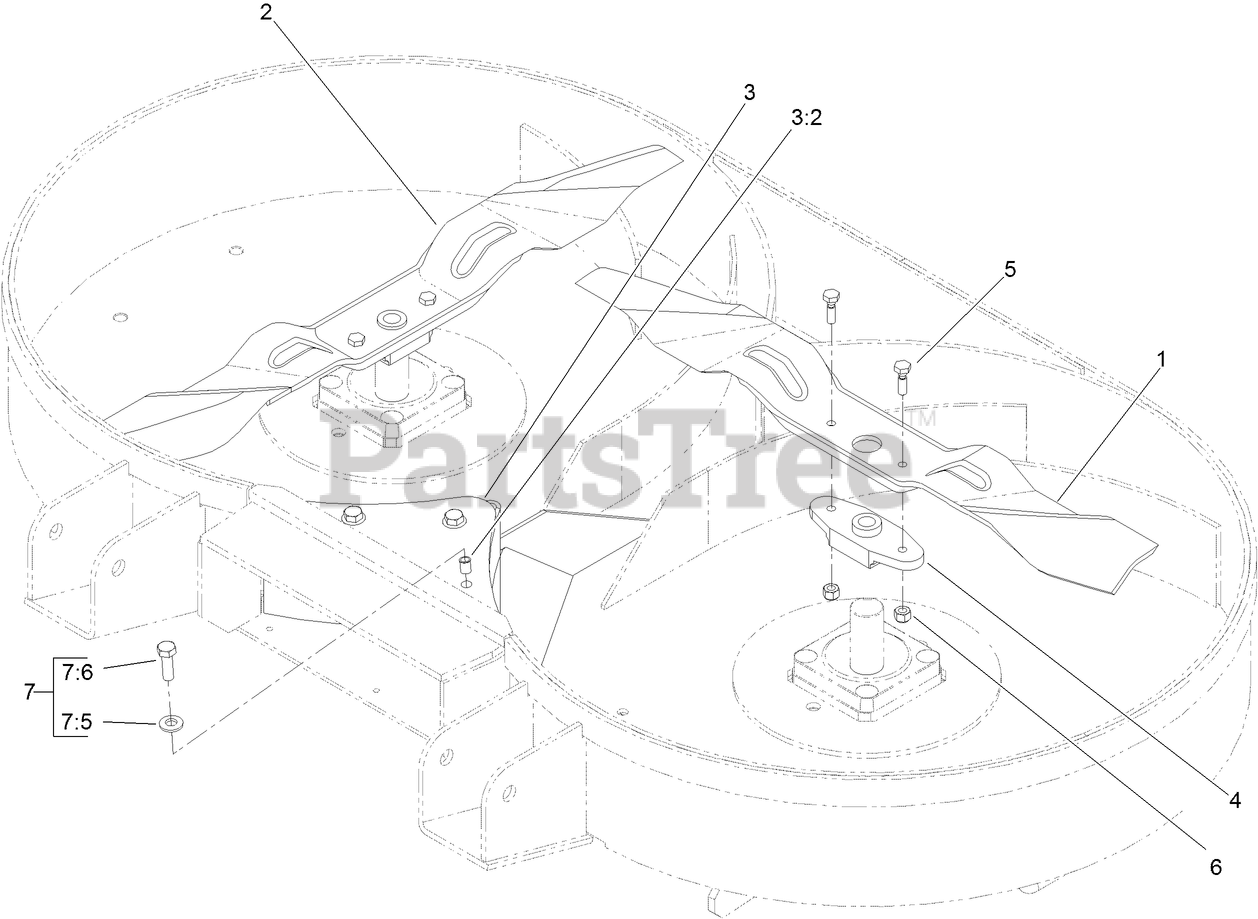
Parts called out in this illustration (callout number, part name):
1	BLADE-MULCHING, 22IN LH
2	BLADE-MULCHING, 22IN RH
3	MULCH PLUG ASM
3:2	NUT-INSERT
4	DRIVER-BLADE
5	BOLT-SHEAR
6	NUT-LOCK, NI
7	BOLT BAG MULCH KIT
7:5	WASHER-SPRING
7:6	SCREW-HH
